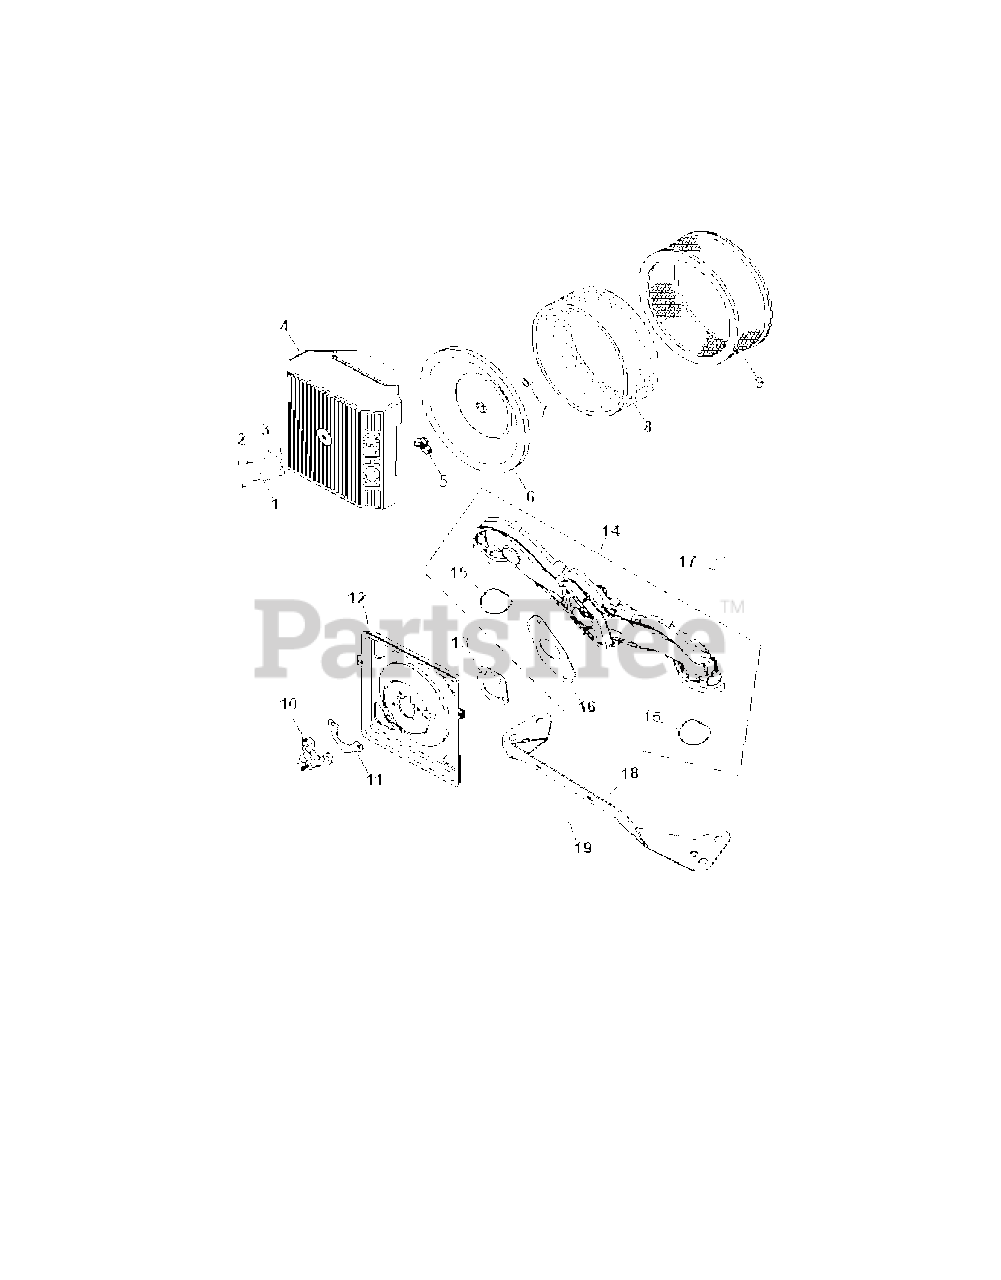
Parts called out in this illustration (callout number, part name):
1	Knob With Seal Kit
4	Air Cleaner Cover
6	Inner Air Cleaner Cover
7	Inner Air Cleaner Seal
8	Precleaner Element
9	Air Cleaner Element
10	Spit Back Cup w/Stud
11	Spit Back Cup Gasket
12	Air Cleaner Base
13	Air Cleaner Gasket
14	Intake Manifold
15	Intake Port O-Ring
16	Carburetor Gasket
17	Hex Flange Screw (M6 x 1.0 x 40)
18	Air Cleaner Bracket
19	Hex Flange Screw (M5 x .8 x 10)
